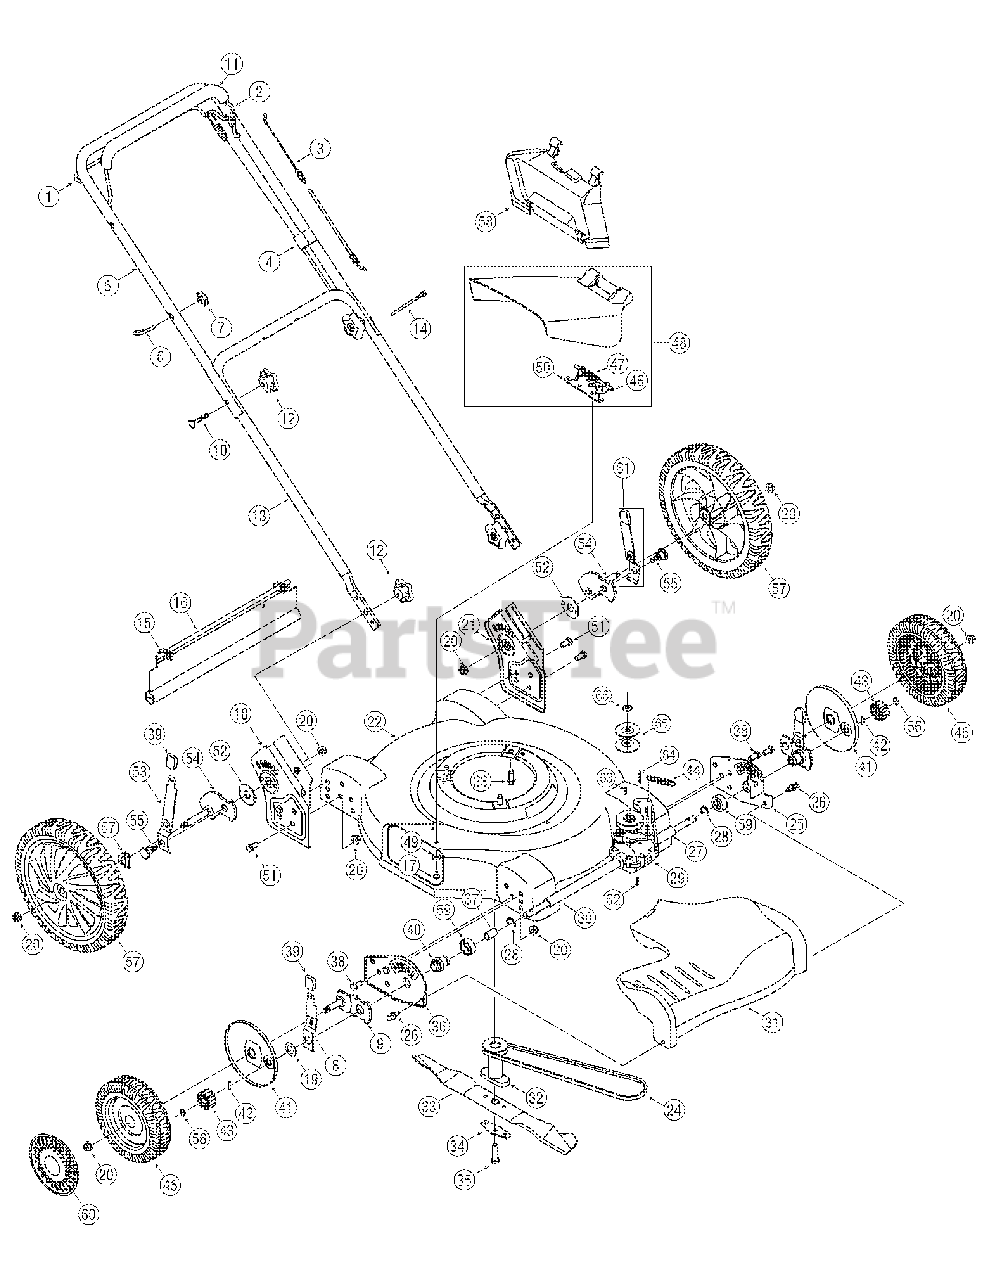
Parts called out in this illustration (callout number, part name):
1	Drive Control Handle
3	Blade Control Cable - 40.75"
4	Drive Control Cable
6	Eye Bolt
7	Wing Nut 1/4-20
8	Spring Lever
9	Pivot Arm Assembly
10	Carriage Bolt 5/16-18
11	Bail Cover
12	Wing Nut
14	Cable Tie
15	Hinge Clip
16	Trail Shield
17	Hex Screw 1/4-20
19	Bell Washer,.760 x 1.25 X .041
20	Lock Nut 3/8-16
23	Hex Washer Scr., 3/8-16 X 1
24	V-Belt, 3L x 32.90
26	Rivet
27	Sleeve Spacer .550 ID
28	Retainer Ring
29	Transmission Assy. Complete
30	Sleeve Spacer .550 ID
31	Transmission Cover
32	Blade Adapter
33	22" Mulching Blade
34	Bell Blade Support
35	Hex Cap Screw 3/8-24
37	Slv. Bearing,.502 x.627 x 1.
38	Hex Cap Screw 3/8-16 x.75
39	Adjustment Knob
40	Bearing Support
41	Wheel Dust Cover
42	Pin
43	Spur Gear 14T - RH
43	Spur Gear 14T - LH
44	Ext. Spring.47 OD x 2.50
45	Front Wheel 8 x 2.125
46	Hinge Pin
47	Torsion Spring
48	Side Discharge Assembly
49	Bell Washer.265 ID x.75 OD
50	Deflector Chute Adapter
51	Hex Cap Screw 3/8-16 x.75
52	Thrust Brg.688 ID x 1.938 OD
53	Spring Lever
54	Rear Pivot Arm Assy - RH
54	Rear Pivot Arm Assembly - LH
55	Shoulder Screw 3/8-16
56	Screw 1/4-20 X .39
57	Rear Wheel 12 x 2.125
58	Mulching Baffle
59	Bearing Support Spacer
60	Hub Cap (If Equipped)
61	Rear Hgt. Adj. Lever Assembly
62	Torx Screw
63	Spirol Pin
64	Dowel pin
65	Pulley, 3.82 x .313 x .68
66	Bell Washer, .325 x .930 x 45
67	Spring Washer, .500 x 1.00
